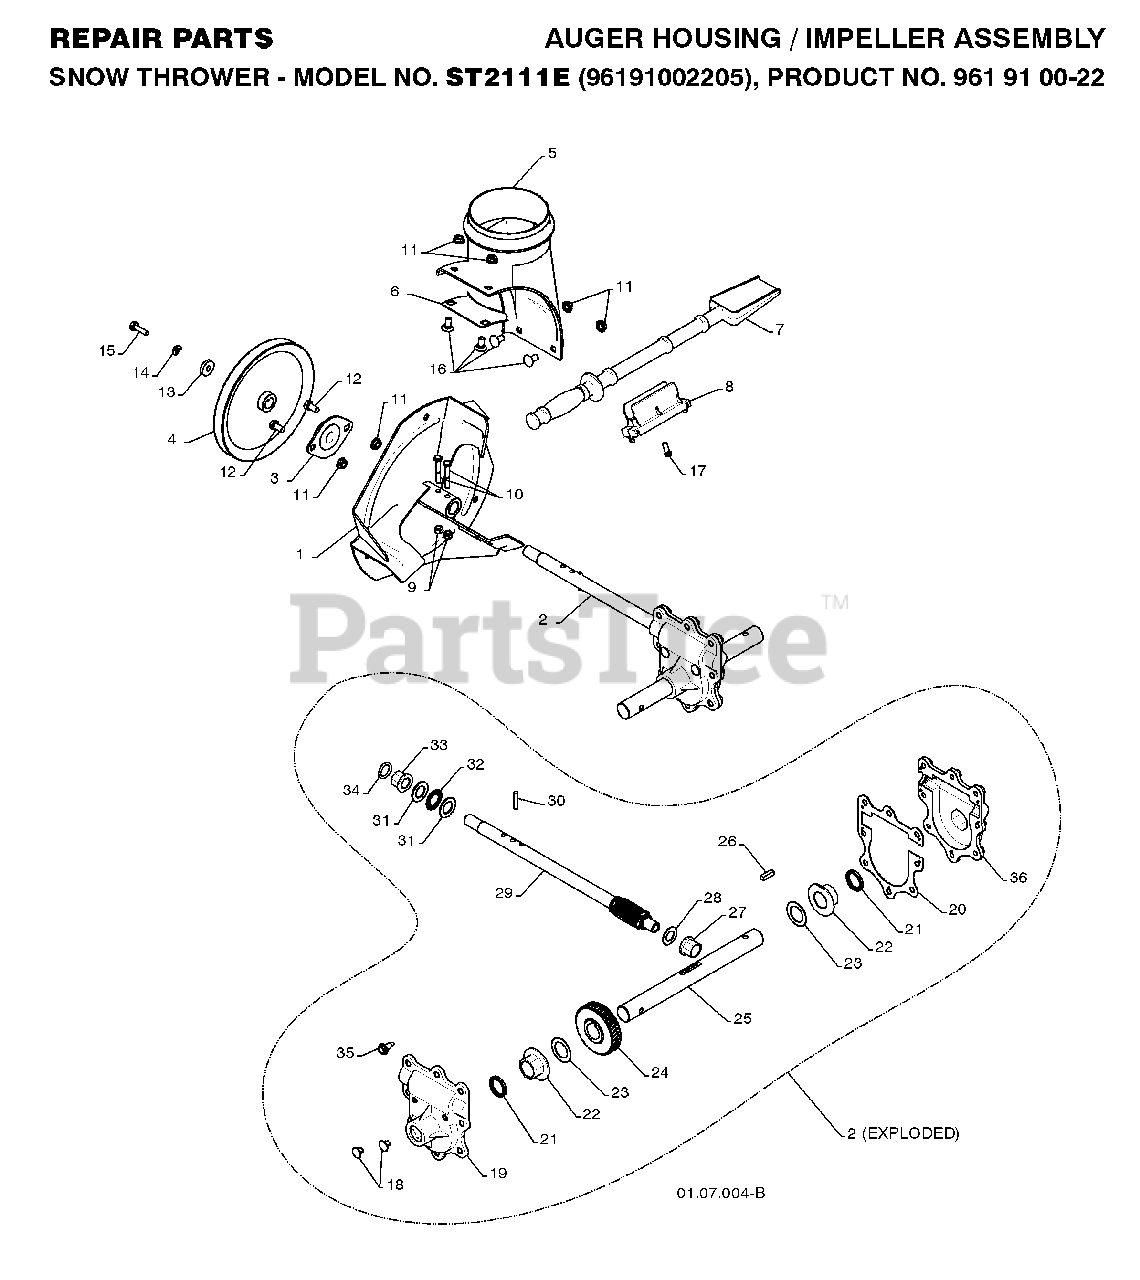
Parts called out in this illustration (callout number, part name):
1	IMPELLER ASSY
2	GEARBOX.ASSEMBLY.AUGER
3	BEARING FLANGE
4	PULLEY, IMPELLER
5	BASE DISCHARGE CHUTE
6	BRACKET, CORNER DISCHARGE
7	CLEAN OUT TOOL
8	CLIP.CLEANOUT.TOOL
9	LOCKNUT
10	SCREW.HEX.HD1/4-20X
11	NUT.FLANGE.5/16
12	BOLT, HEX HEAD 5/16-18
13	WASHER, FLAT
14	LOCKWASHER
15	CAPSCREW.HX.HD.5/16-18X1.00.NY
16	BOLT.CARRIAGE.5/16-18X
17	SCREW.HWH.13-16-5.8.BZP
18	CASE PLUG
19	GEARBOX HOUSING-RH
20	GEARBOX GASKET
21	OIL SEAL
22	FLANGE BUSHING-1"
23	WASHER TRUST 1"
24	WORM GEAR
25	AUGER SHAFT
26	KEY, SQUARE 1/4 X .875
27	FLANGE BUSHING-5/8
28	WASHER, THRUST 5/8
29	SHAFT, IMPELLER
30	PIN, ROLL 3/16 X 1-1/8
31	WASHER, THRUST 3/4
32	BEARING TRUST 3/4
33	BUSHING, FLANGE 3/4
35	HEX SCREW-5/16 X 3/4
36	GEARBOX HOUSING - LH
